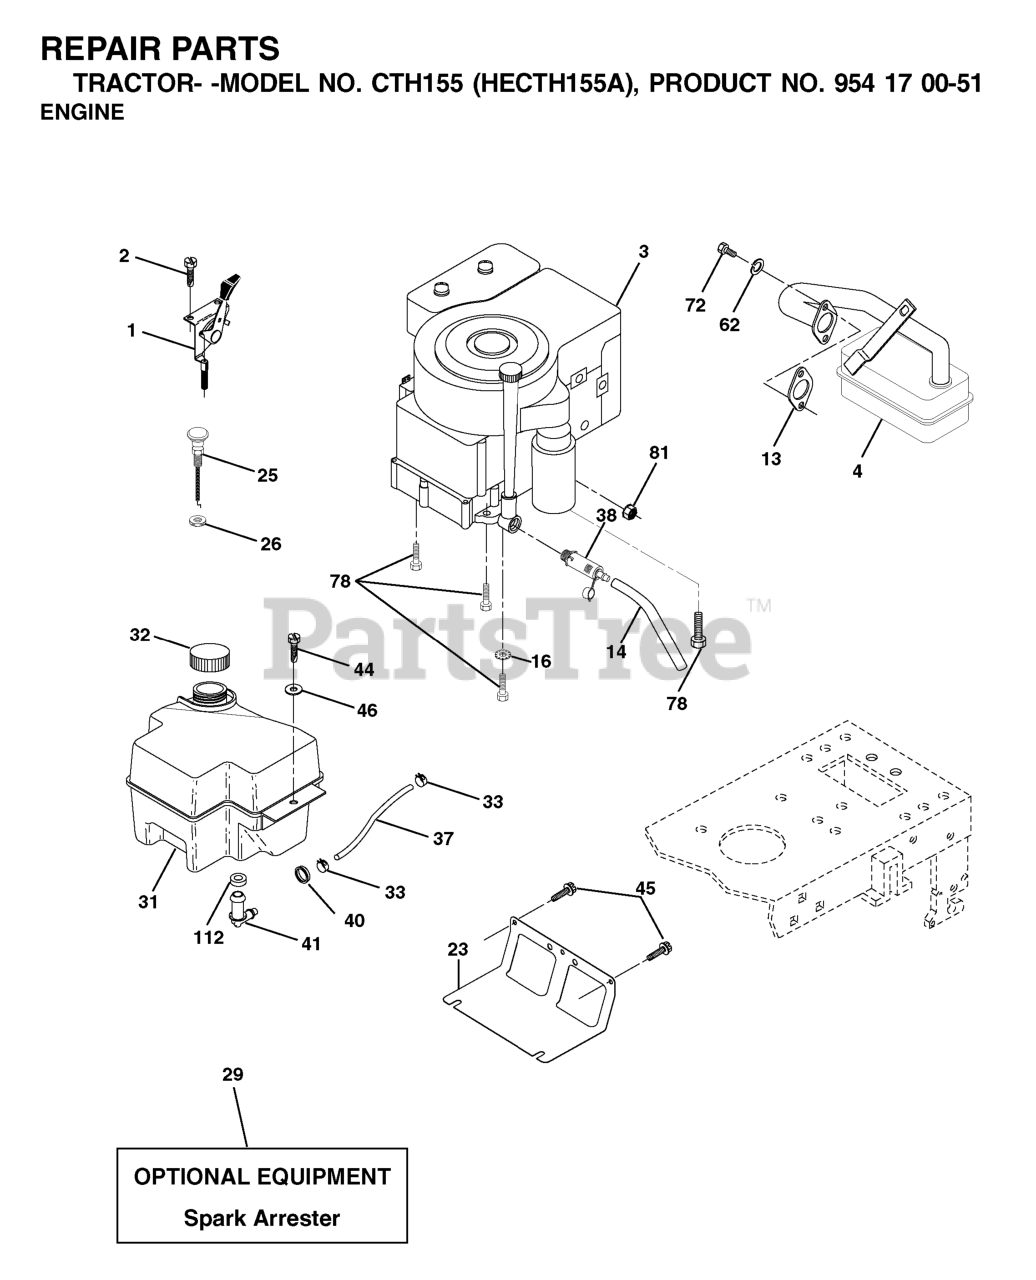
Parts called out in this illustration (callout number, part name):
1	CONTROL.THROTTLE/CHOKE.BLACK
2	SCREW
4	MUFFLER.LT.BRIGGS.14HP.IC/OHV
13	REPL BY 532 27 22-93
14	TUBE, DRAIN OIL ASM.
16	LOCKWASHER
23	SHIELD.BROWNING.DBR.GUARD
26	Nut Keps 3/8 - 24 UNF
29	KIT.SPARK ARRESTOR 794945 B&S
31	GAS TANK 2GAL
32	FUEL CAP
33	HOSE CLAMP
37	LINE.FUEL.20
38	PLUG, OIL DRAIN EASY
40	BUSHING.SNAP.NYL.BLK.
41	STEM FUEL TANK
44	SCREW HEXWSHR 1/4-20X3/4
45	SCREW, 3/8-16X3/4
62	WASHER.LOCK.HVY.HLCL.SPR.5/16
72	SCREW
78	SCREW.3/8-16
81	NUT
112	BUSHING OUTLET T
